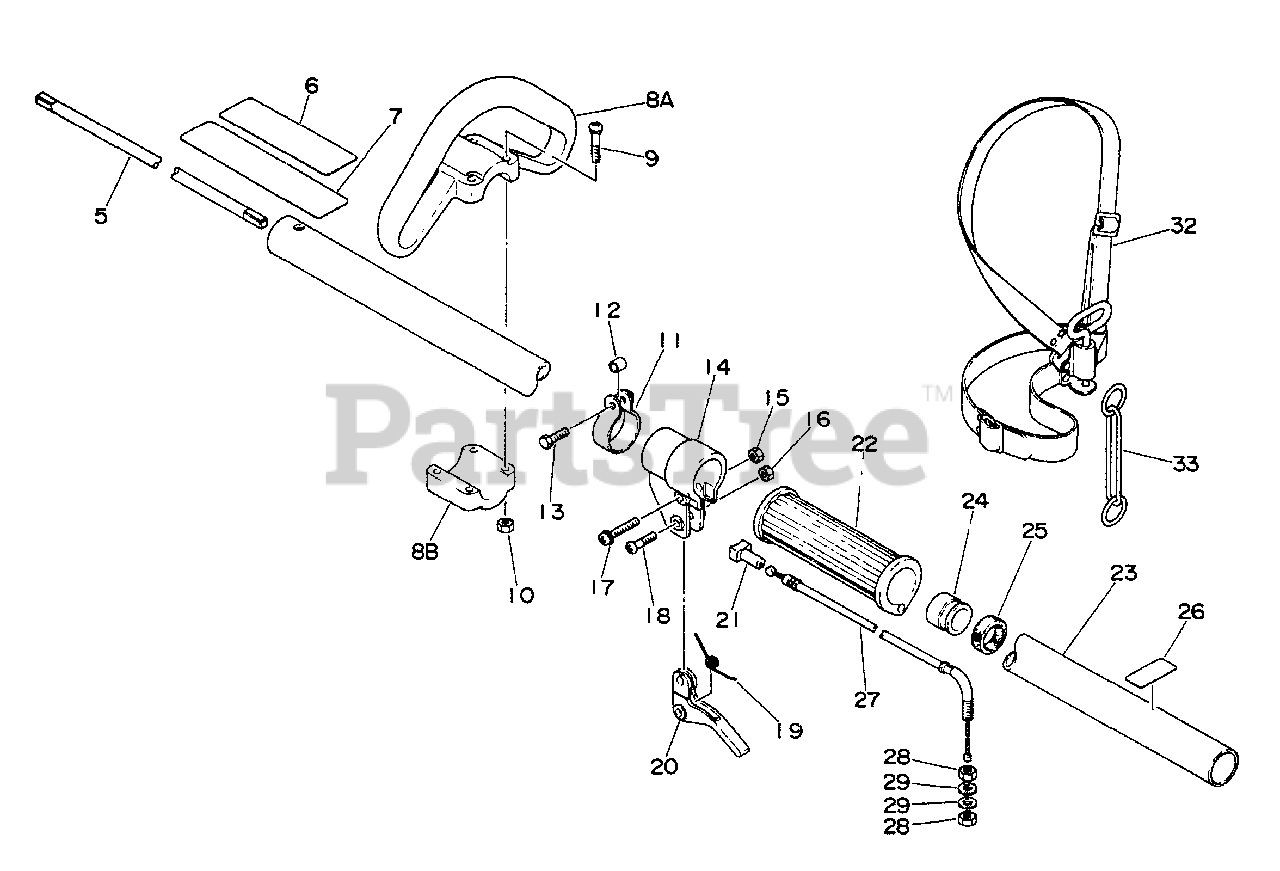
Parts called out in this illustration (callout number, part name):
5	DRIVESHAFT
6	LABEL - CAUTION
7	LABEL - CAUTION
8	LOOP HANDLE ASSY
8A	LOOP HANDLE ASSY
8B	LOOP HANDLE ASSY
9	SCREW - 5X35
13	BOLT - 5X18
14	BRACKET, TRIGGER
16	LOCKNUT - 5
17	SCREW - 5X30
18	SCREW - 5X30
19	SPRING, TRIGGER
20	TRIGGER, THROTTLE
21	GUIDE, CABLE
22	GRIP
23	MAIN PIPE ASSY
26	LABEL - ALIGNMENT
27	CABLE, THROTTLE
29	WASHER - 6
32	SHOULDER STRAP ASSY
